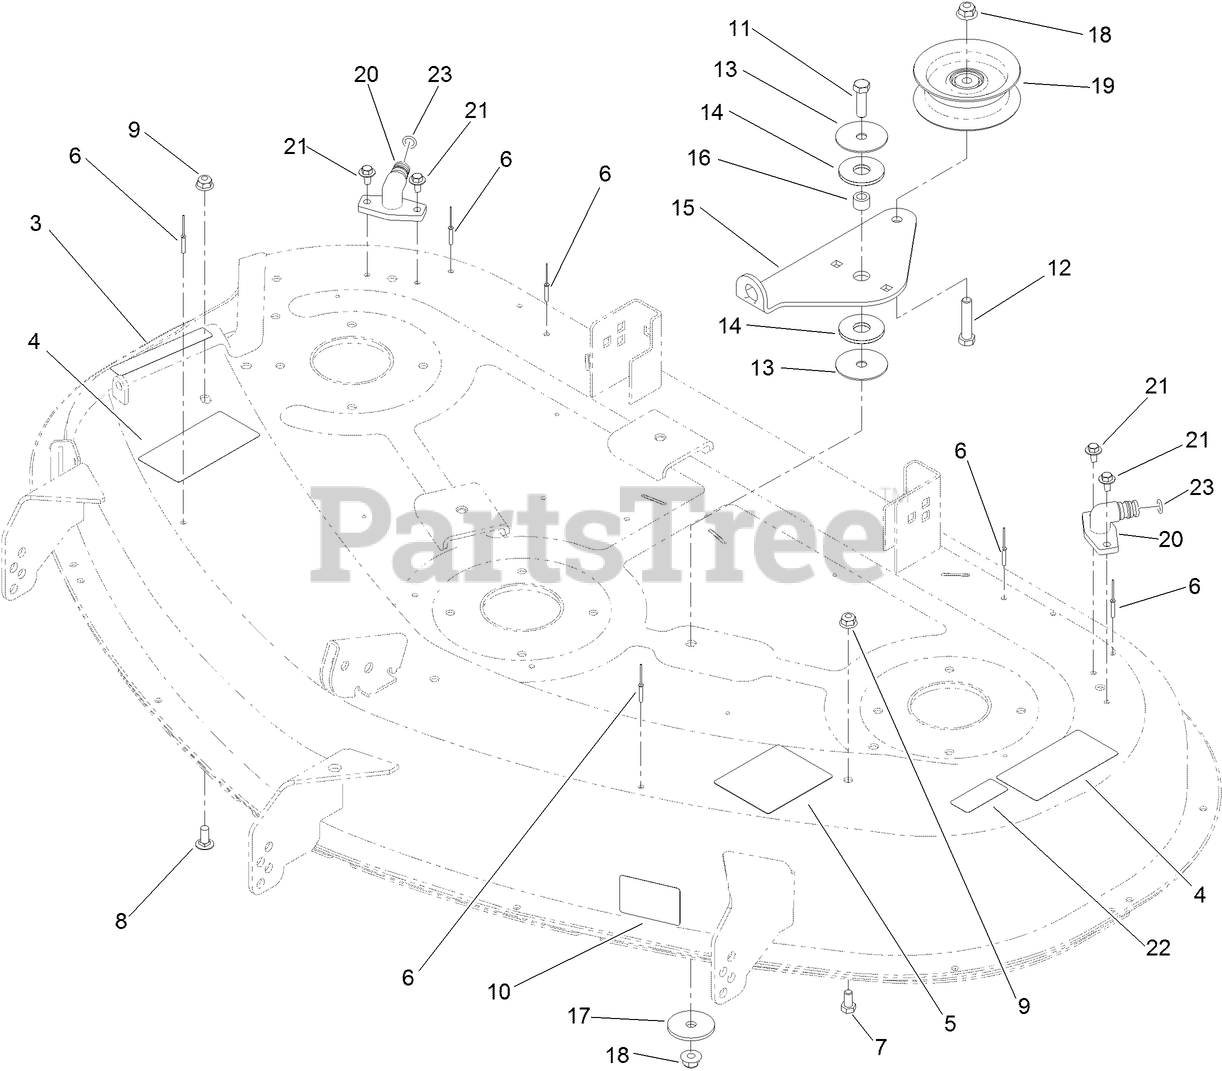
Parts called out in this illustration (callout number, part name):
3	DECAL-DANGER
4	DECAL-DANGER, DECK
5	DECAL-ROUTING, BELT
6	RIVET-BLIND
7	SCREW-HH
8	SCREW-CARR
9	NUT-HF, NI
10	DECAL-SCALP, ANTI
11	SCREW-HH
12	SCREW-HH
13	WASHER
14	WASHER-FRICTION, COMPOSITE
15	ARM-IDLER
16	SPACER
17	WASHER-REBOUND
18	NUT-HF, NI
19	PULLEY-IDLER, FLAT
20	FITTING-WASHOUT
21	SCREW-HHFTF
22	SERVICE DECAL
23	O-RING
